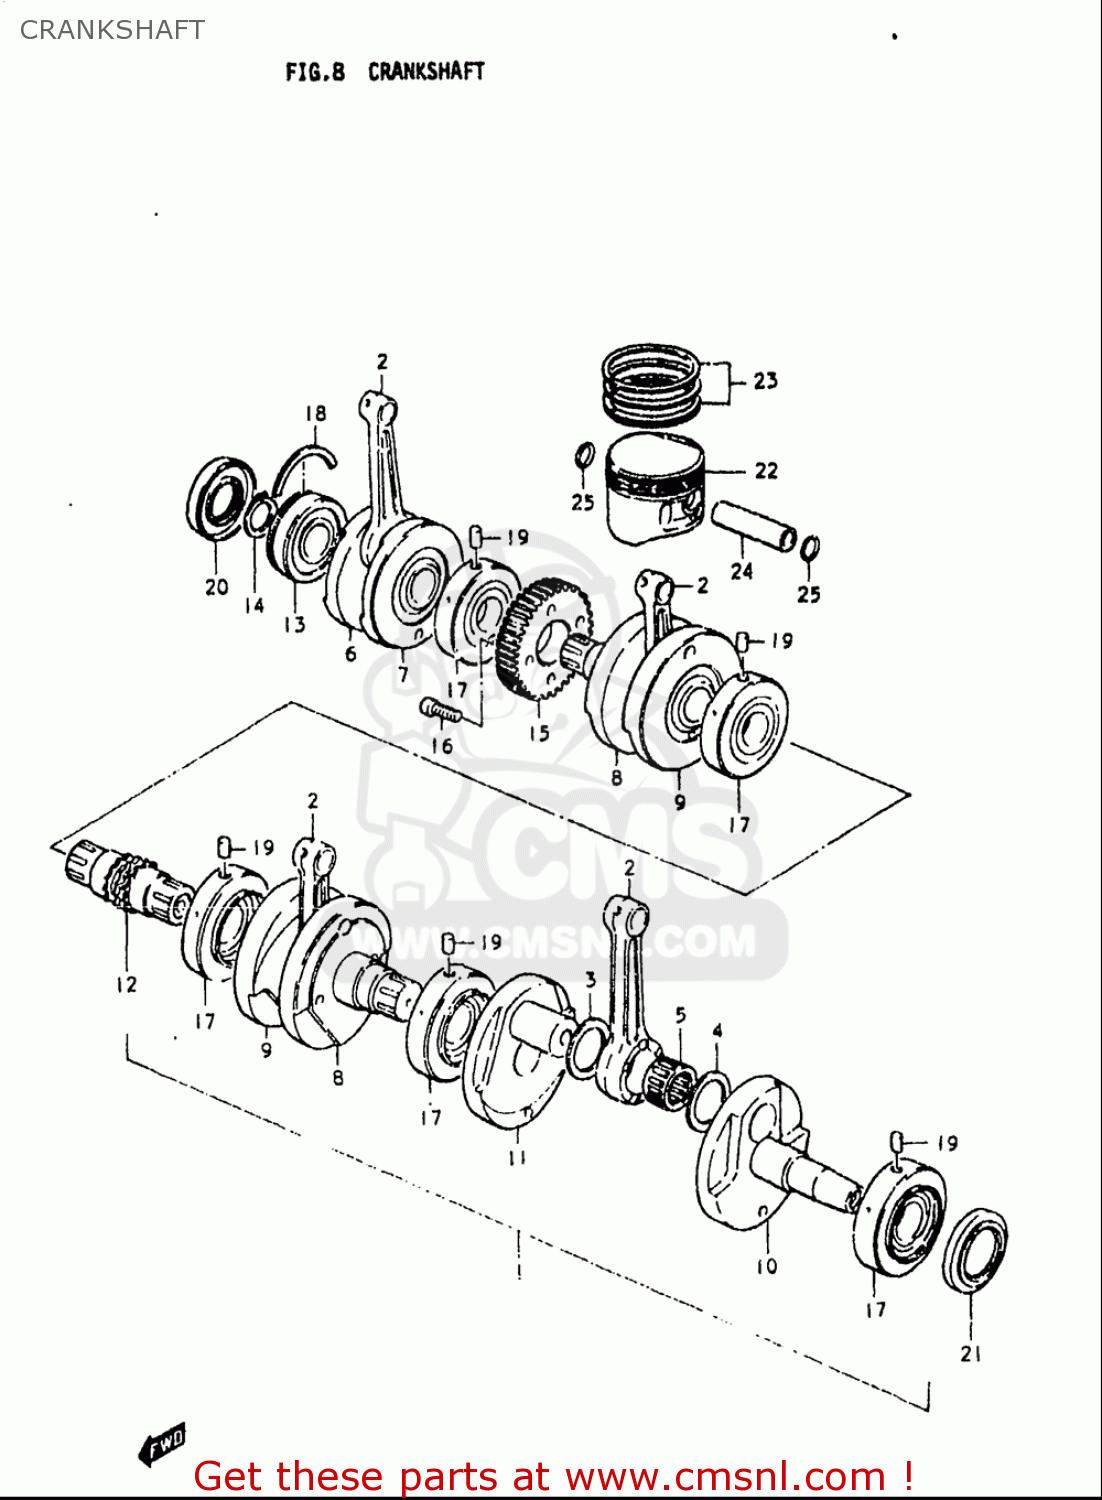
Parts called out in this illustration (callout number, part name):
3	WASHER (28X48X2)
5	BEARING(28X38X19.8)
13	BEARING(30X72X19)
14	CIRCLIP
16	BOLT
18	C RING
19	PIN
20	SEAL,OIL(30X72X11)
21	SEAL,OIL(47.3X60X6.5)
22	PISTON
23	RING SET,PISTON
24	PIN,PISTON
25	RING,SNAP 16MM
